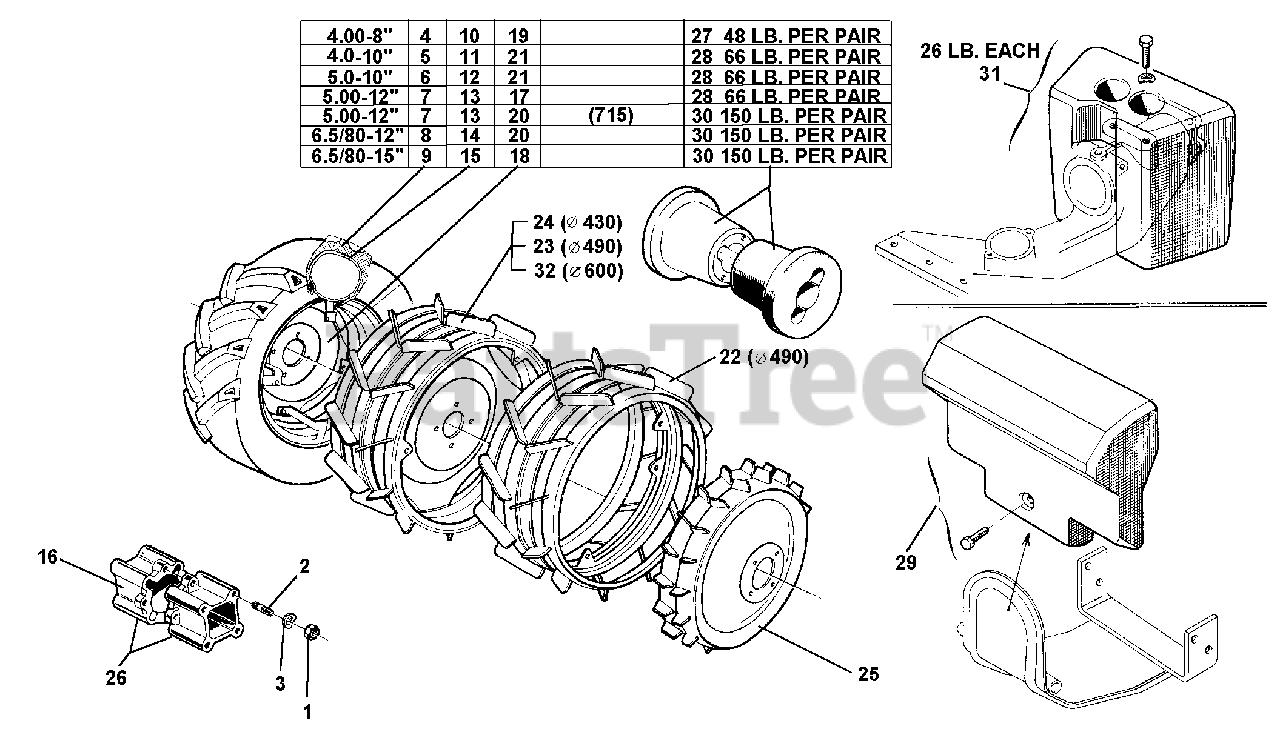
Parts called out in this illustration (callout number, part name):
2	STUD M10 X 40 X 22 X 14
3	WASHER, LOCK 10.5
4	TIRE TRACTOR 4.00 X 8
5	TIRE TRACTOR 4.0 - 10
6	TIRE 5.0 X 10
7	TIRE 5.00 - 12
8	TIRE 6.5/80 - 12
9	TIRE TRACTOR 6.5/80 X 15
10	TUBE 4.00 X 8
11	TUBE 4.0 - 10
12	TUBE 5.0 - 10
13	TUBE 5.00 - 12
14	TUBE 6.5/80 X 12
15	TUBE 6.5/80 X 15
16	WHEEL SPACER
17	RIM, 12 OFFSET COUPLING
18	RIM 5 J 15 INCH ADJ. TRACK
19	WHEEL, DISK, 2.50 - 8
20	RIM 5JA - 12 INCH. ADJ. TRACK
21	RIM 3.50 D 10 (INCH) C.VAR.COM.
22	RINGS, 19" CAGE WHEELS (PR)
23	WHEELS, STEEL CAGE, 19" (PR)
24	WHEELS, STEEL CAGE, 17" (PR)
25	NARROW NURSERY WHEELS (PR)
26	WHEEL SPACERS, 2.5" (PR)
27	WEIGHTS FOR 4.00 X 8, (48#)(PR)
28	WEIGHTS FOR 10"/12", (66#)(PR)
29	FRONT WEIGHT ASBY., (35#)(EA)
30	WEIGHTS,6 X 12/6.5 X 15,(150#)(PR)
31	WEIGHT FOR CUTTER BAR, (EA)
32	WHEELS, STEEL CAGE, 24" (PR)
